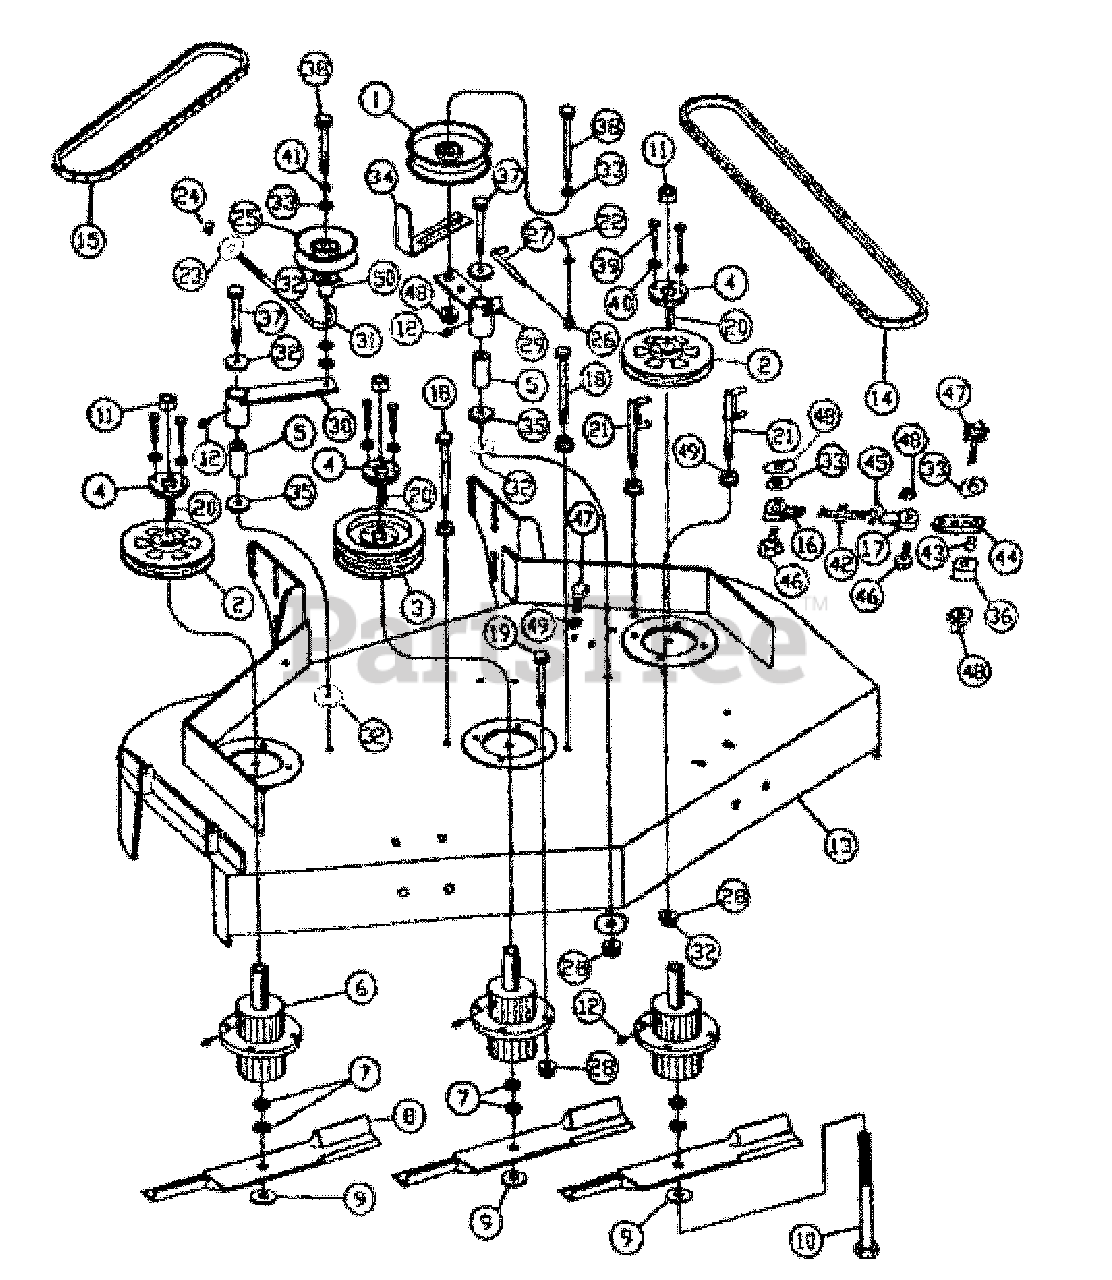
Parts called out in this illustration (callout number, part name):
1	100-013 IDLER PULLEY
2	100-025 PULLEY SINGLE
3	148-004 PULLEY DBL
4	100-026 H-BUSHING
5	100-024 PIVOT HUB
6	100-021 CUTTING HOUSE AS
7	100-022 SPACER 6
8	BLD 48` - WALKABOUT
9	100-023 WASHER
10	200-023 BOLT M16`1.5`245
11	200-017 NEX NUT M16`1.5
12	GREASE FTG (10 PACK) 200-026
13	148-002 BLUE DECK 48
14	148-006 BELT 48`
15	148-007 BELT BLD TO BLD
17	100-027 ROD END RH
18	200-028 NUT FLANGE M8
19	200-018 HEX BOLT M10-35
20	100-014 KEY 6.35`6`50
22	200-014 COTTER PIN 2`20
23	200-028 NUT FLANGE M8
25	148-008 IDLER PULLEY
26	100-018 SWIVEL
28	200-006 NYLON NUT M10
29	100-020 IDLER ARM WLDT.
30	148-009 DECK IDLER ARM
31	148-009 ROD BELT TENSION
32	100-019 WASHER
33	WASHER, 3/8 STD FLAT
34	100-033 BELT GUIDE
35	100-015 WASHER 2`26ID
36	100-031 SPACER 12
37	M10X1.5X70 HHB GR8.8
38	200-022 HEX BOLT M10`65
39	M8X1.25X30MM HHB
40	5/16HELICAL L-WASHER
41	3/8HELICAL L-WASHER
42	100-030 TURN BUCKLE ROD
43	100-032 LINK BUSHING
44	100-029 LINK IDLER ARM
46	200-018 HEX BOLT M10-35
47	200-019 HEX BOLT M10-40
48	200-006 NYLON NUT M10
49	200-016 NUT FLANGE M10
50	148-011 SPACER 16
